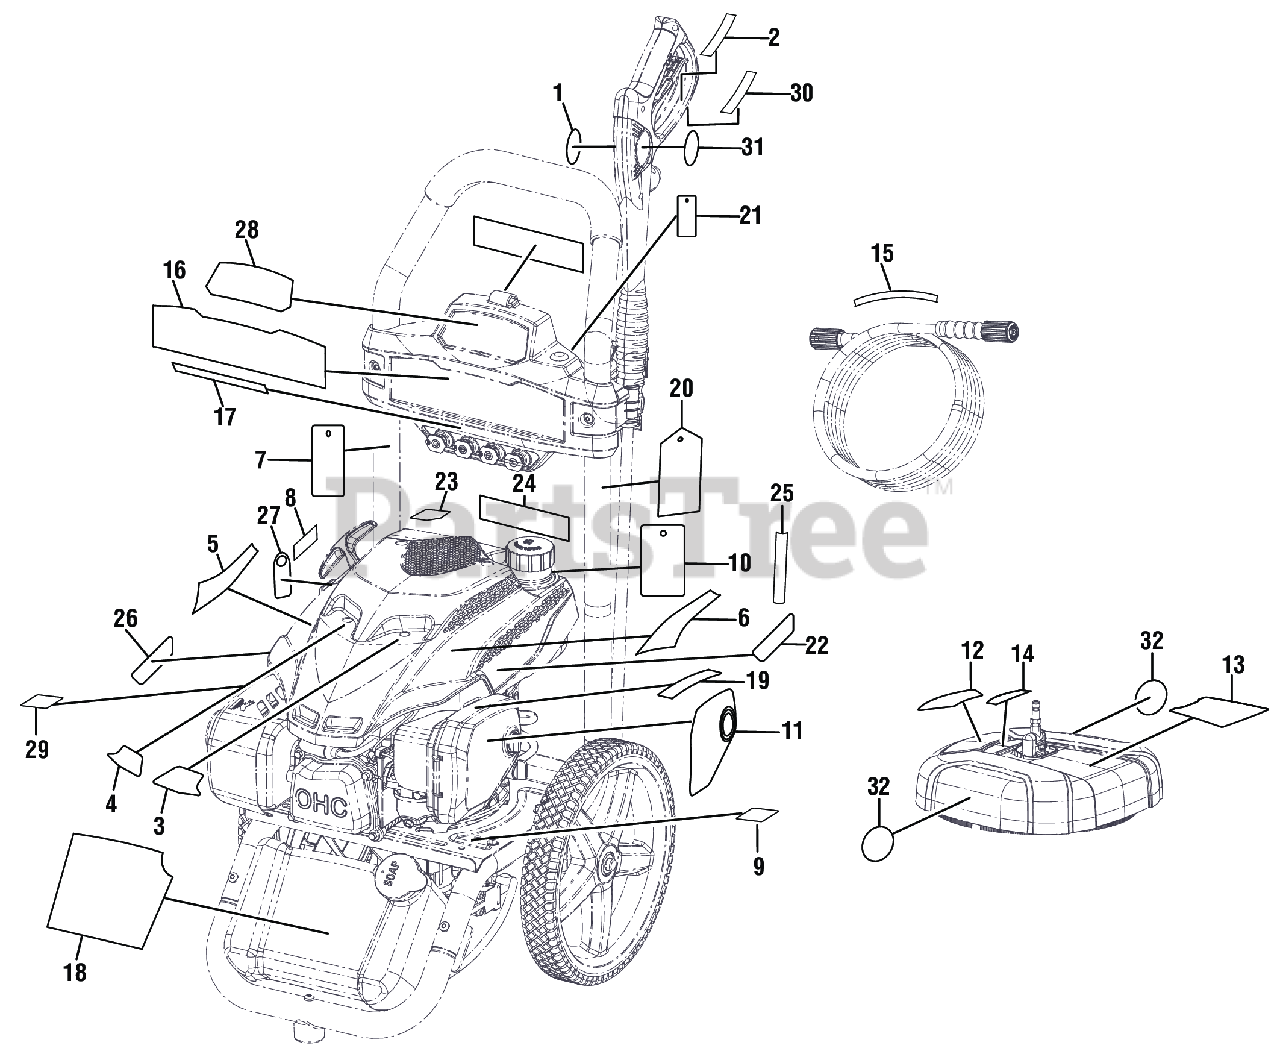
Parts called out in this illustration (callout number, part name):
1	Powerstroke Trigger Wand Logo Label
2	Label (Trigger Handle Warning, French & Spanish)
3	Vent Label (Left)
4	Vent Label (Right)
5	Yamaha Label (Right)
6	Yamaha Label (Left)
7	Danger Hang Tag
8	Add Oil Label
9	Data Warnings Label (English)
10	Fuel Storage Hangtag
11	EMC ICES-2/NMB-2 Label (Canada)
12	Surface Cleaner Logo Label (PS803188)
13	Surface Cleaner Danger Label (PS803188)
14	Surface Cleaner Performance Label (PS803188)
15	High Pressure Hose Hangtag
16	Logo Label (PS803188)
17	Nozzle Selection Label
18	Detergent Tank Label
19	Warning Label (Inquiries)
20	Nozzle Hangtag
21	Quick Start Hangtag (PS803188)
22	Choke/Fuel Valve Label (PS803188)
23	E85 Label
24	Danger Label
25	Label (Combustion Warning)
26	Hot Surface Label
27	Oil Dipstick Hang Tag
28	Performance Label (PS803188)
29	Data Warnings Label (PS803188)
30	Trigger Handle Specifications Label
31	Label (Trigger Handle Warning, English)
32	No Hands Label (Cleaning Deck)
